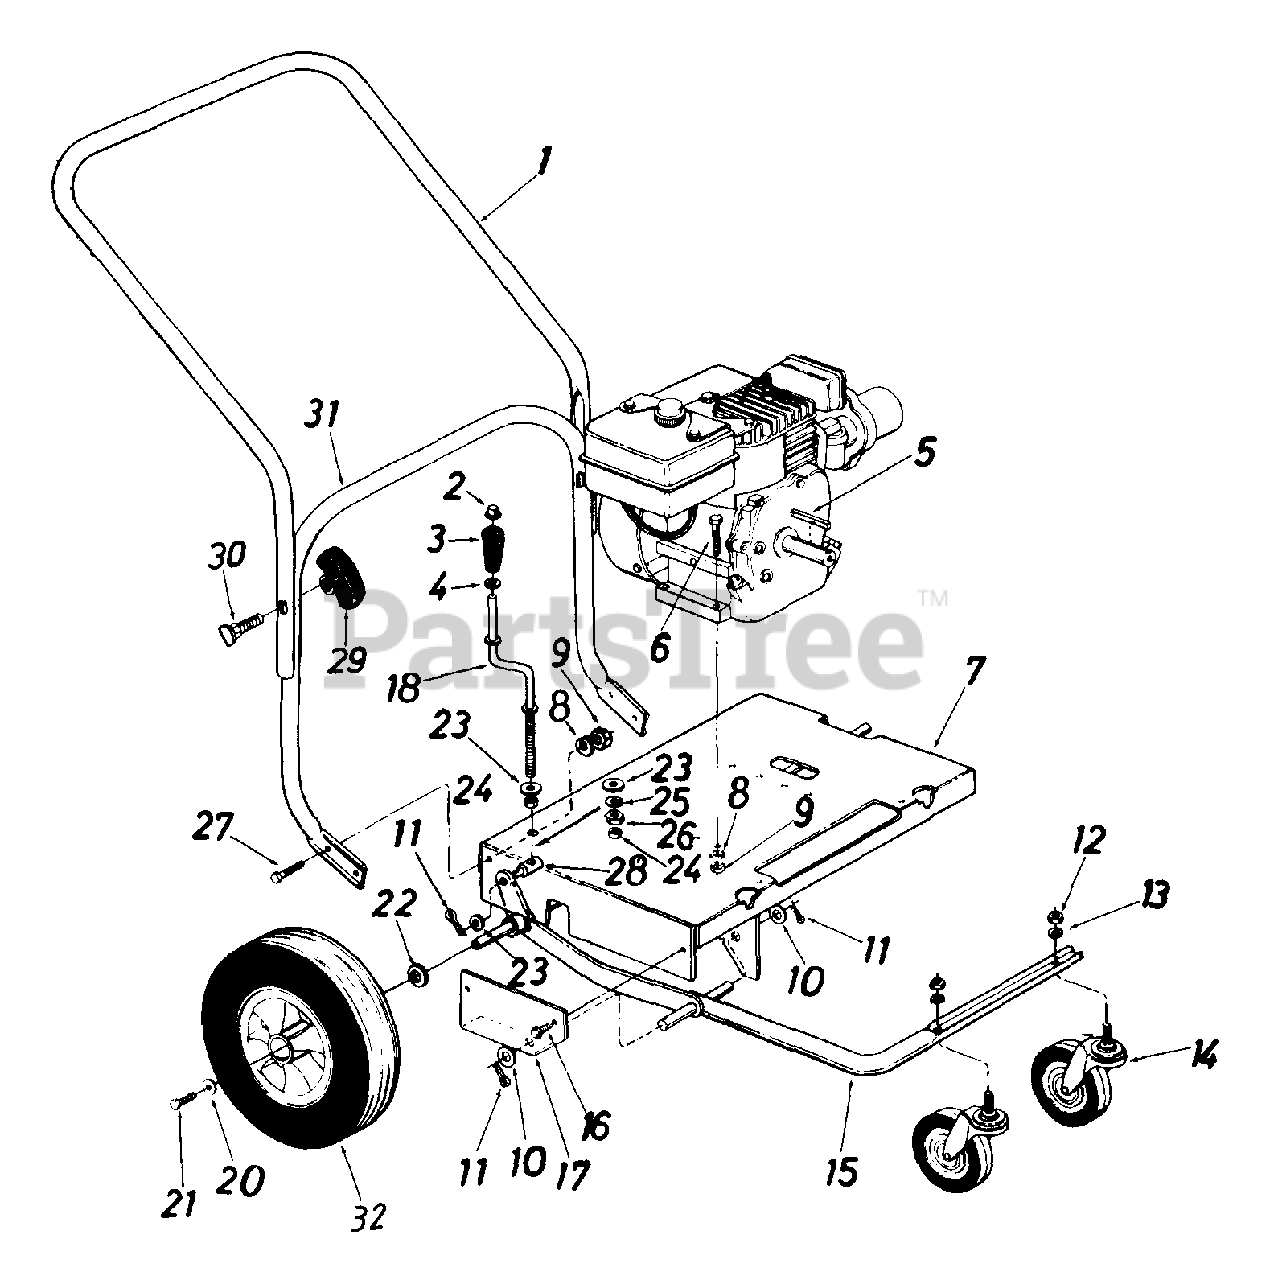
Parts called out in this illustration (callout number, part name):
2	Push Nut 3/8" Rod
3	Crank Knob
4	Fl-Wash..385" I.D. x .62"
5	Sq. Key 1/4" x 2.0" Lg.
6	Hex Bolt 5/16-18 x 1.50" Lg.
7	Engine Mounting Frame Ass'y.
8	L-Wash. 5/16" I.D.
9	Hex Nut 5/16-18 Thd.
10	Fl-Wash..63" I.D. x 1.25"
11	Cotter Pin 1/8" Dia, x 1.0"
12	Hex Nut 1/2-13 Thd.
13	L-Wash. 1/2" I.D.
14	Swivel Caster Wheel 5" Dia. x 1.25"
20	Fl-Wash..34" I.D. x .87" O.D.
21	Hex Locking Bolt 5/16-24 x .64" Lg.
22	Fl-Wash.
23	Fl-Wash..38" I.D. x .57"
24	Spacer .382" I.D. x .50" x .180" Lg.
25	L-Wash. 3l8" I.D.
26	Hex Nut 3/8-8 Thd.
27	Hex Bolt 5/16-18 x .75" Lg.
28	Ferrule
29	Hand Knob
30	Carriage Bolt 5/16-18 x 2.0"
